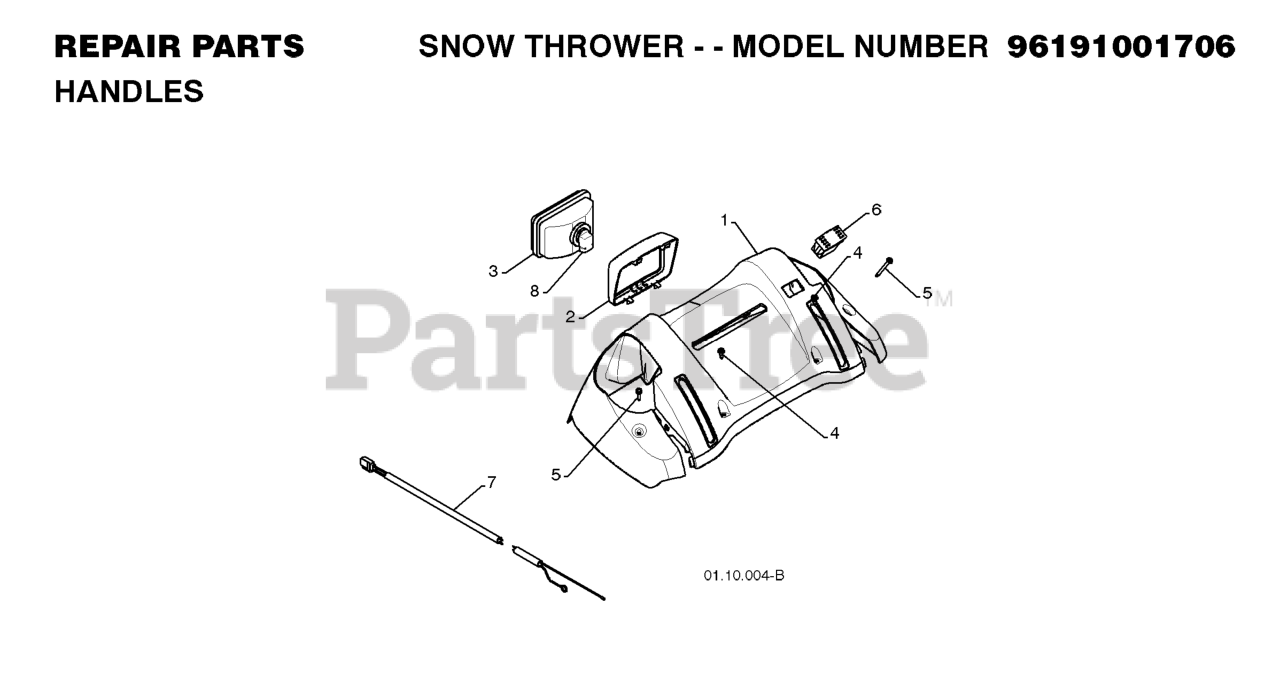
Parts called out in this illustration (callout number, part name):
1	PANEL.CONSOLE.LIGHT.REM.SWITCH
2	BEZEL.HEADLIGHT.BLACK
3	HEADLIGHT.HALOGEN.SNOW
4	SCREW, HEX HEAD, TAPPING
5	SCREW, HEX HD TAPPING #10-24 1
6	SWITCH.HEATED.GRIP
7	HARNESS.WIRE.LIGHT/GRIP.SNOW
8	BULB.HEADLIGHT.HALOGEN.
